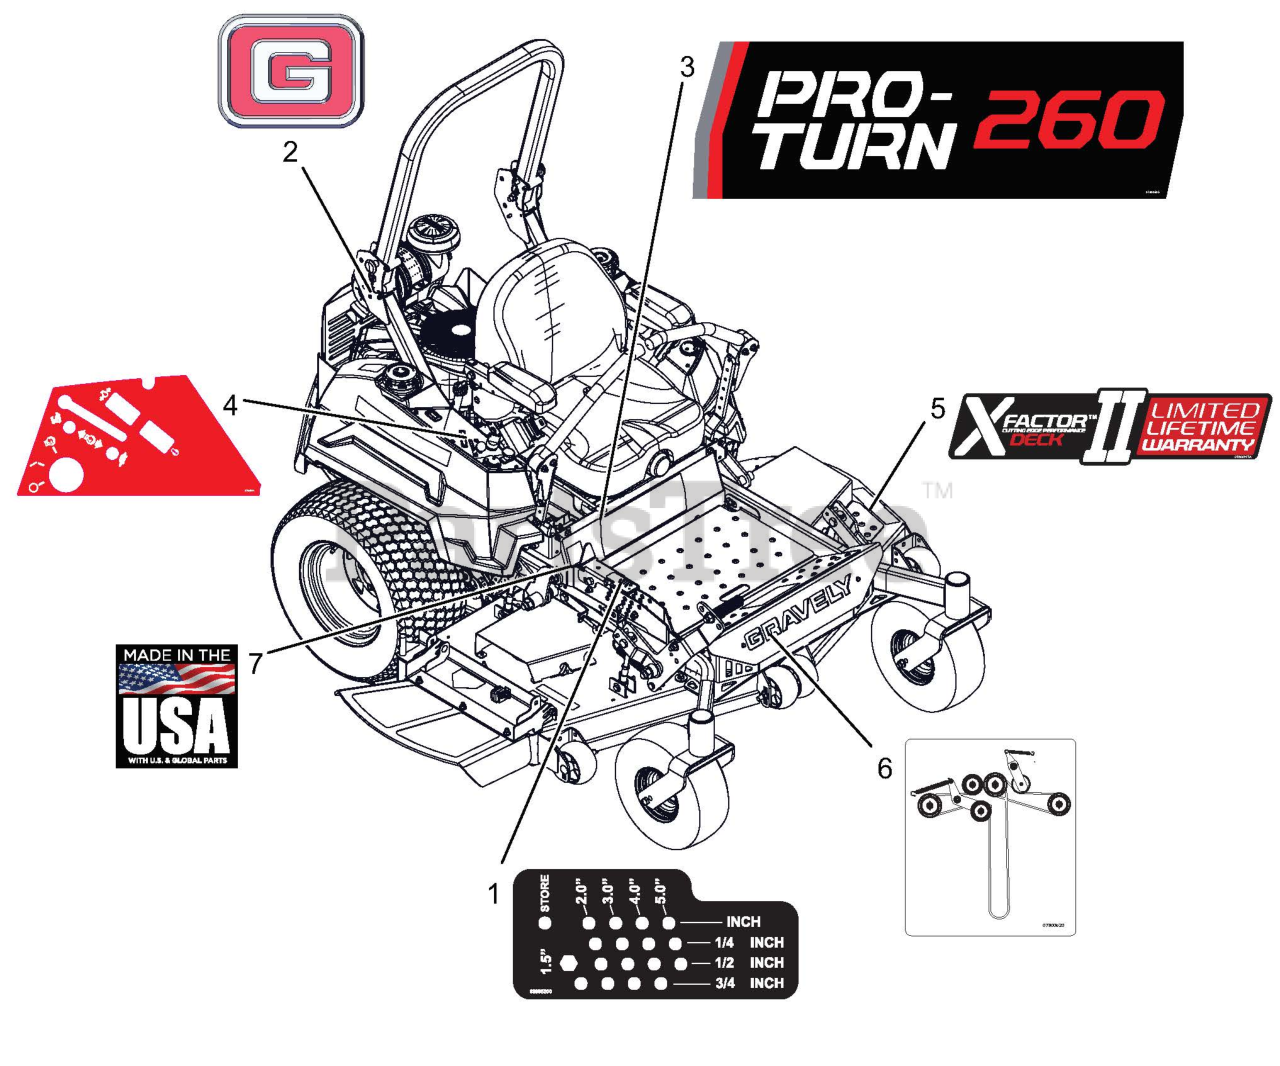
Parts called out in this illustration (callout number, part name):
1	DECAL, HEIGHT OF CUT
2	DECAL, GRAVELY BRAND
3	DECAL, PRO-TURN 260
4	DECAL, EFI CONTROL PANEL
5	DECAL, X-FACTOR DECK
6	DCL,BELT ROUTE-RH BK-SIDE IDLR
7	DECAL, MADE IN USA
